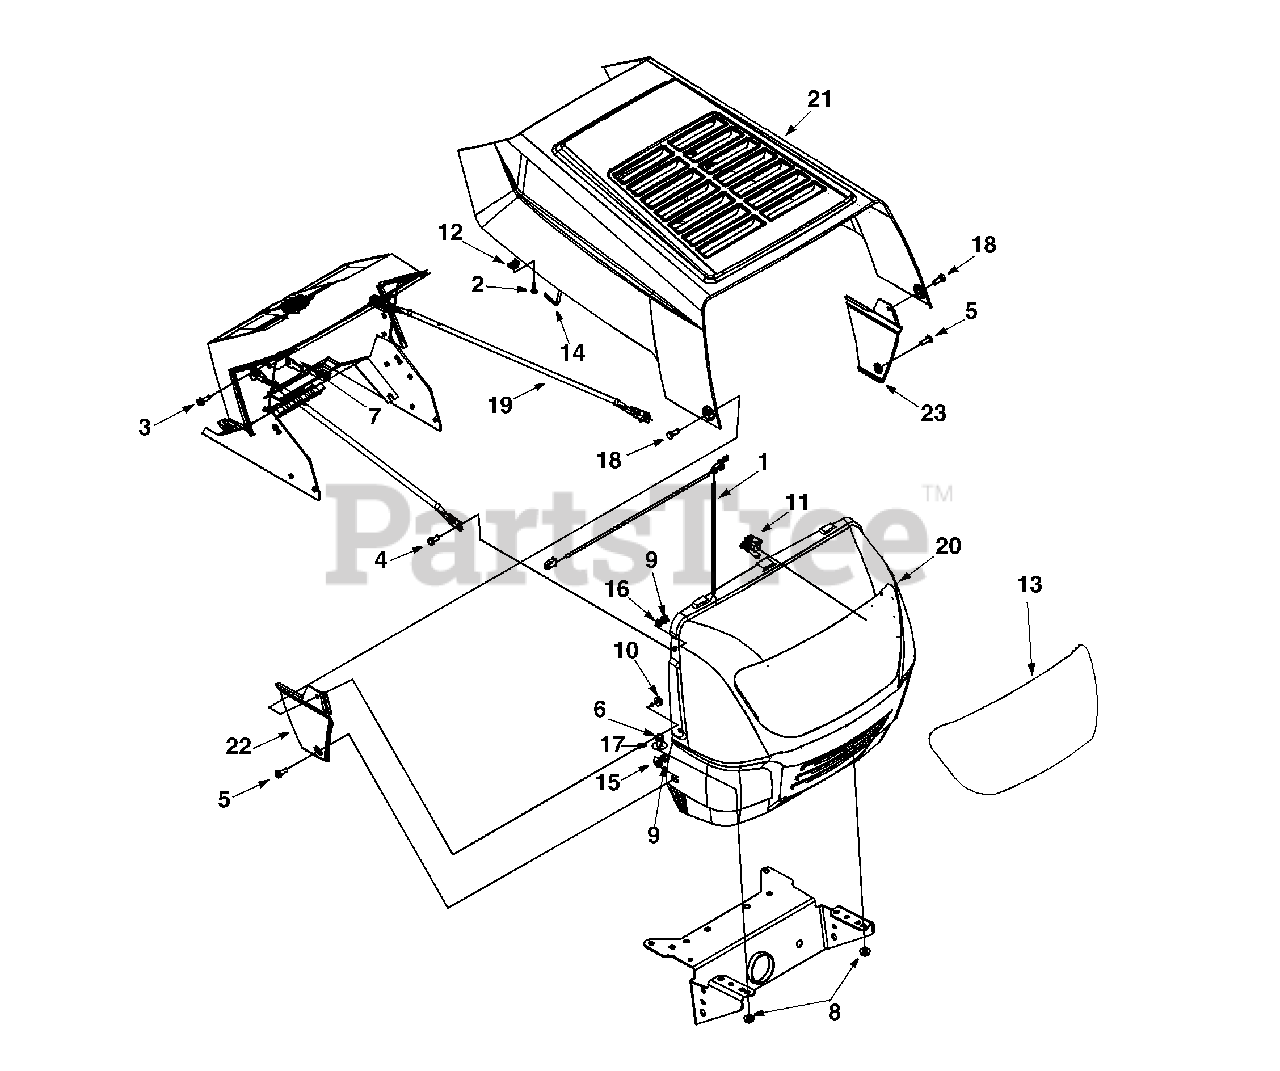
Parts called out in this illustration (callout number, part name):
1	Headlight Harness Assembly
2	Truss. Mach. Scr. #10-24 x .75"
3	Hex TT-Tap Scr. 1/4-20 x .75" Lg.
4	Hex Bolt 1/4-20 x .5/8" Lg.
5	Pan Hd. Mach. Scr. 1/4-20 x .75"
6	Hex Bolt 5/16-18 x .75" Lg.
7	Speed Nut 1/4-20 Thd.
8	Flange L-Nut 5/16-18 Thd.
9	Hex Sems Nut 1/4-20 Thd.
10	Hex Flange L-Nut 1/4-20 Thd.
11	Socket
12	Speed Nut
13	Lens
15	Bell Wash. .265" I.D. x .75" O.D.
16	L-Wash. 1/4" I.D.
17	Fl-Wash. .349" I.D. x 1.0" O.D.
18	Shldr Bolt. .375" I.D. x 1.25" O.D.
